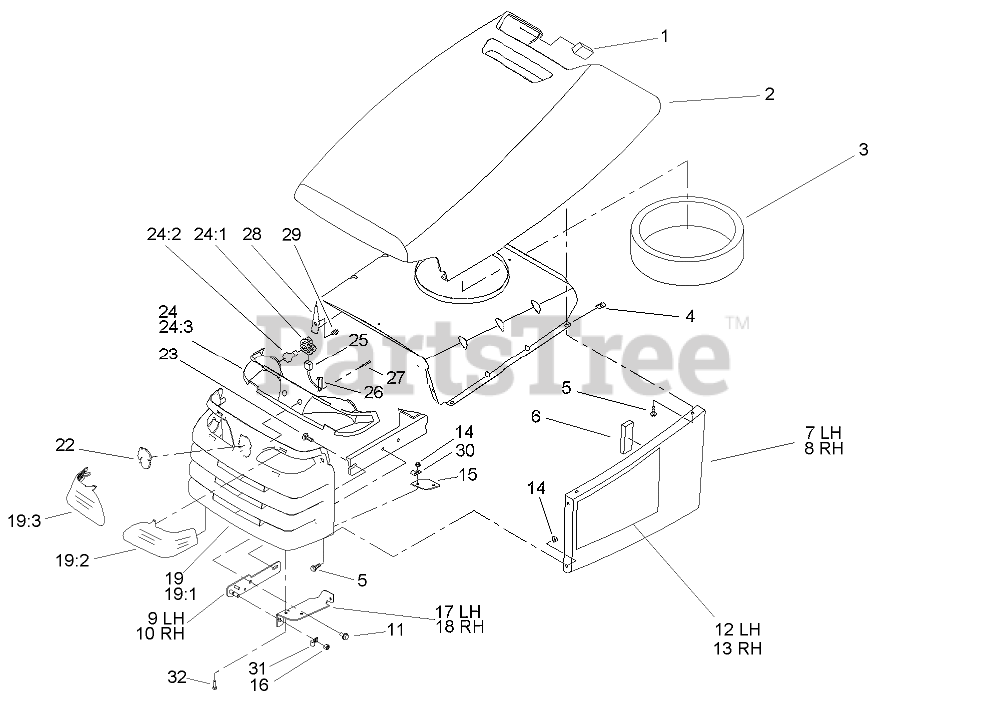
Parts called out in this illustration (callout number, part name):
1	FOAM-HOOD
2	HOOD ASM
3	SEAL-AIR INLET, TWIN
5	SCREW-HWH
6	FOAM-SIDEPANEL
7	HOOD-SIDE, LH
8	HOOD-SIDE, RH
9	BRACKET-HINGE, LH
10	BRACKET-HINGE, RH
11	SCREW-HWHTF
12	DECAL-HOOD, LH
13	DECAL-HOOD, RH
14	NUT-LOCK, HHF
15	HINGE-HOOD
16	NUT-LOCK, NI
17	BRACKET-HOOD, HINGE, LH
18	BRACKET-HOOD, HINGE, RH
19	Grille ASM
19:1	GRILLE
19:2	LENS-LH
19:3	LENS-RH
22	EMBLEM
23	SCREW-CARR
24:1	SOCKET-HEADLIGHT
24:2	BULB
24:3	REFLECTOR
25	HARNESS-WIRE, HEADLIGHTS
26	TIE-CABLE
27	SCREW
28	BAFFLE-HOOD, UPPER
29	SCREW-PLASTITE
30	CLAMP-R
31	CLAMP-R
32	SCREW-HH
